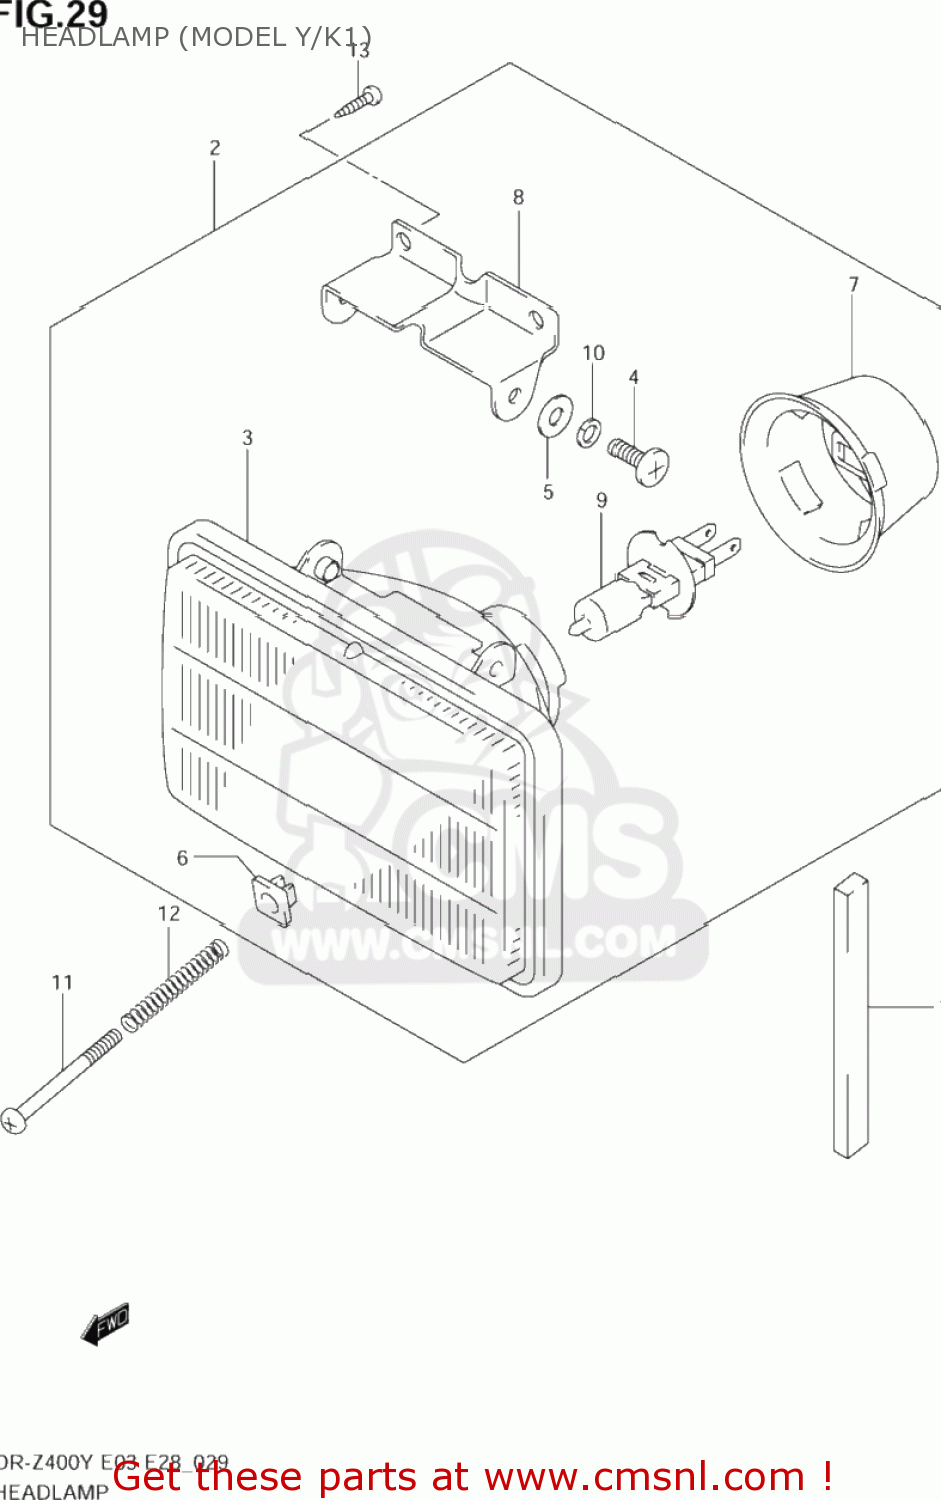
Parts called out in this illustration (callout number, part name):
1	PROTECTOR(50X50X5)
2	HEADLAMP ASSY
3	UNIT,LAMP
4	SCREW
5	WASHER
6	NUT,ADJUSTING
7	COVER,SOCKET
8	BRACKET,LAMP
9	BULB(12V55W)
10	WASHER,LOCK
11	SCREW(4X45)
12	SPRING,HEAD LAMP ADJUSTER
13	SCREW
